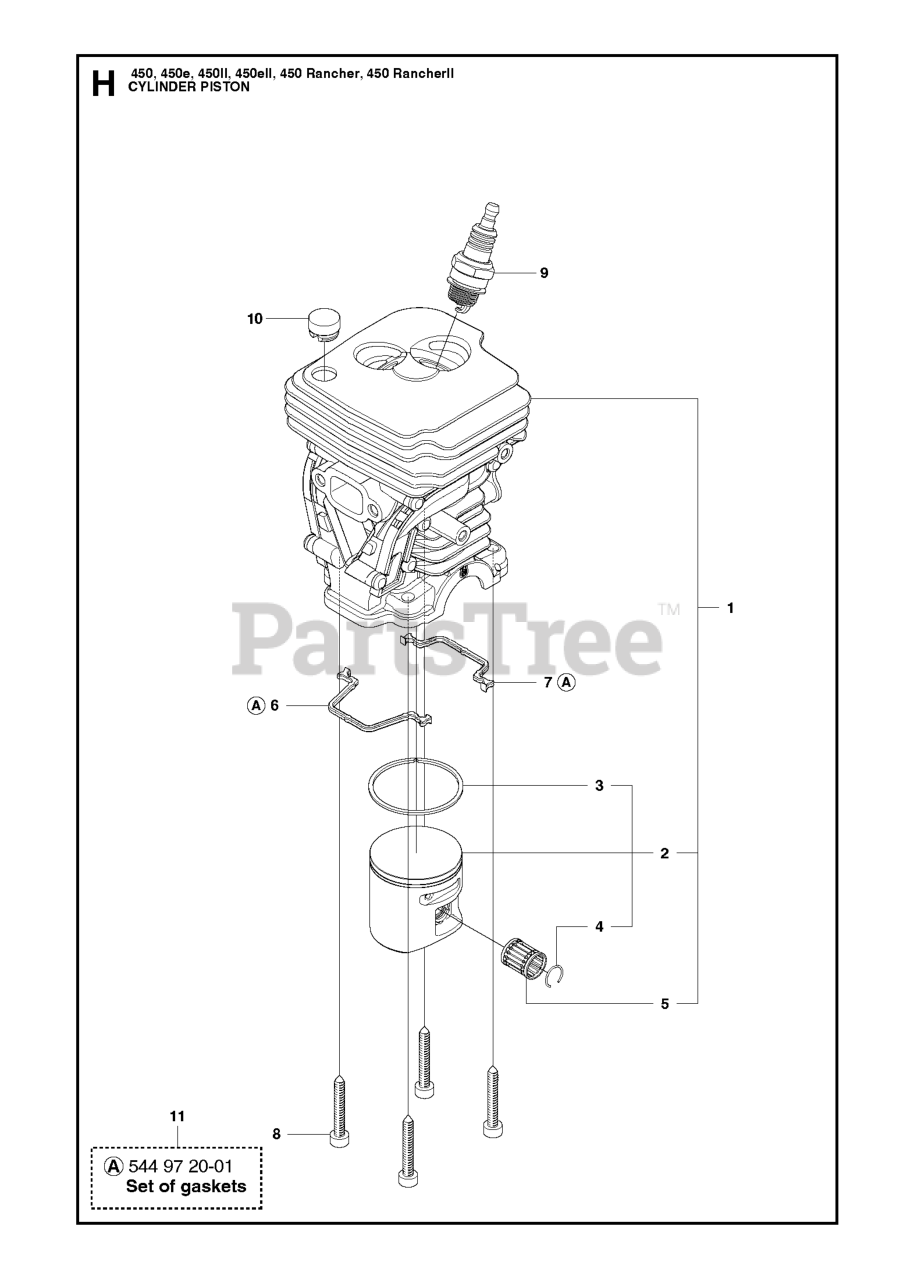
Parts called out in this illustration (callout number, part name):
1	CYLINDER
2	PISTON ASSY
3	PISTON RING
5	SUPPORT BUSHING
9	SPARK PLUG M14X1.25 NGK BPMR7A
11	GASKET KIT
